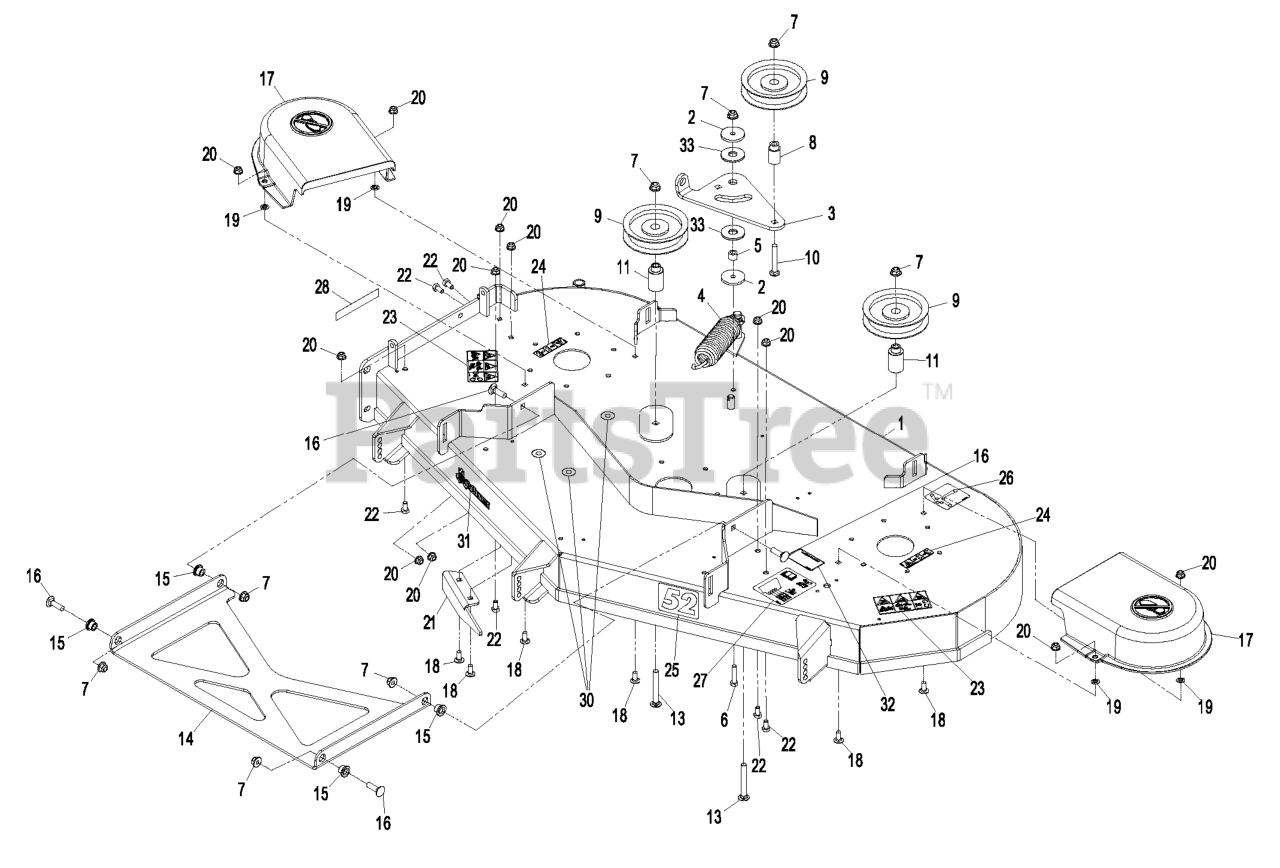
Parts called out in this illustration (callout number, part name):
1	ASM,52" DECK W/ DECALS
2	WASHER-PLAIN
3	ARM,IDLER
5	BUSHING-LEVER, LIFT
6	SCREW-HH
7	NUT-HF, NI
8	BUSHING-IDLER
10	SCREW-CARR
11	BUSHING-IDLER
13	BOLT-CARRIAGE
14	STRUT-DECK
15	BUSHING-FLANGED
16	BOLT-CARR
17	SHIELD-BELT
18	SCREW-CARR
19	RING-RETAINING, BOLT
20	NUT-HF, NI
21	BAFFLE-DISCHARGE
22	SCREW-HH
23	DECAL-DANGER
24	DECAL-WARNING, BELT SHIEL
25	DECAL,DECK 52
26	DECAL-ROUTING, BELT
27	DECAL-ROLLER, ANTI-SCALP
28	DECAL-DANGER
30	DECAL-HOLE COVER
32	DECAL,BLADE TORQUE
33	WASHER-FRICTION, COMPOSIT
